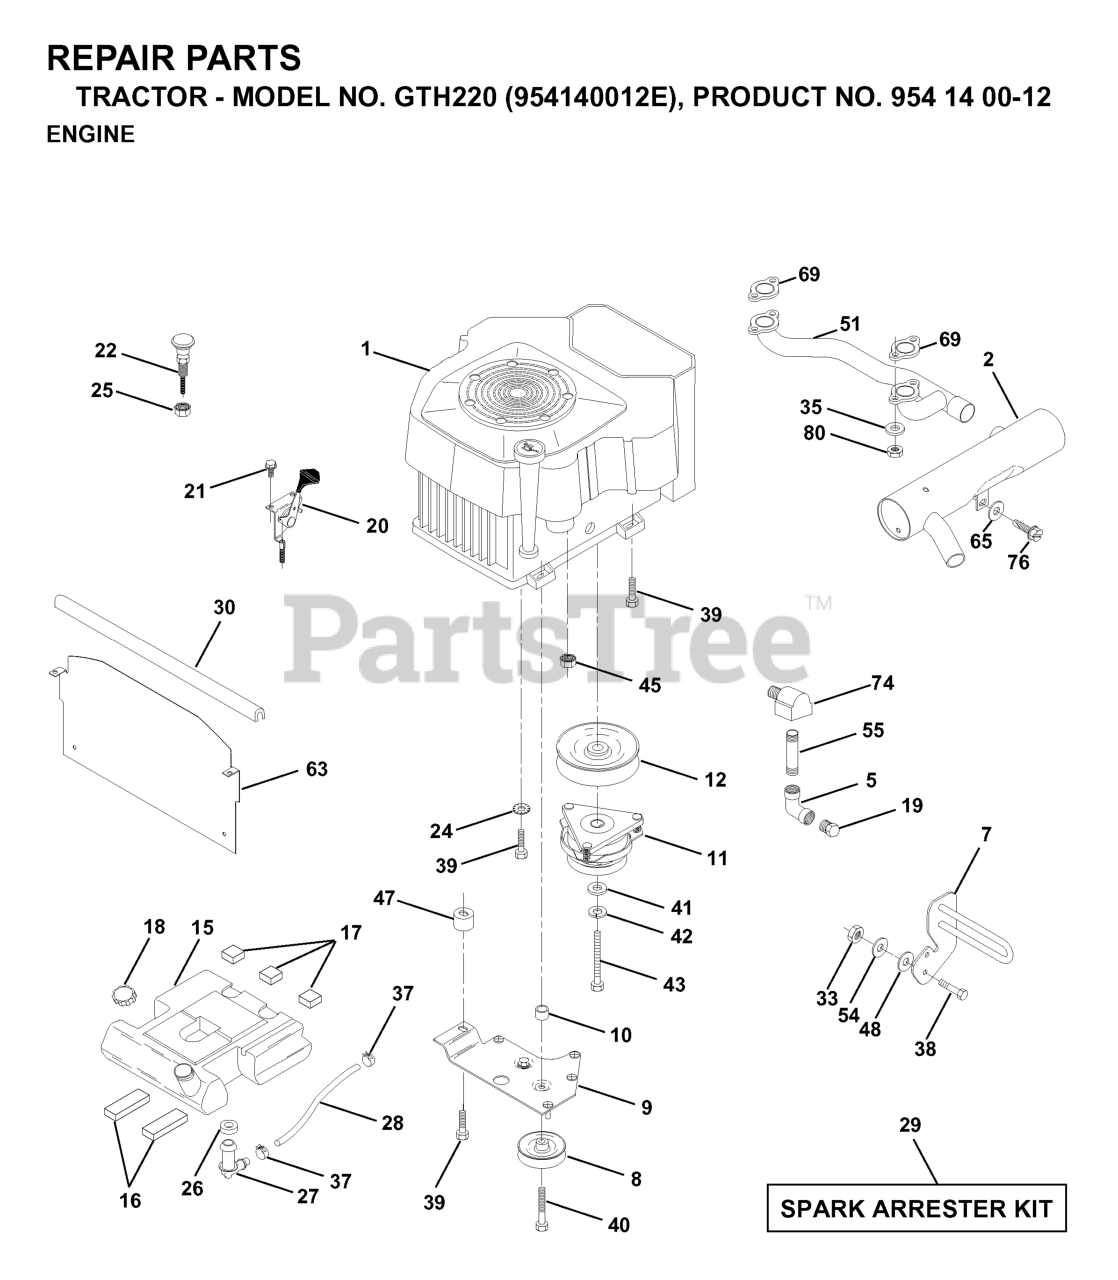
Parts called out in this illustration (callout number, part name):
5	ELBOW
8	RP.IDLER GROOVED
9	KEEPER ASM. BELT ENGINE VGT 96
11	CLUTCH ELECTRIC
12	PULLEY ENG VGT ELECT CLUTCH
15	FUEL TANK 3.5G
16	PAD IDLER TI
17	PAD-SPACER LT
18	FUEL CAP
20	THROTTLE CONTROL
21	SCREW LT
22	CHOKE CONTROL
24	LOCKWASHER
25	Nut Keps 3/8 - 24 UNF
26	BUSHING OUTLET T
27	STEM FUEL TANK
28	HOSE
30	EXTRUSION HOOD
33	NUT
37	HOSE CLAMP
38	BOLT
39	SCREW TT 3/8-16X2-1/4 UNC
40	Screw TT 3/8-16 x 4 unc
42	LOCKWASHER
43	BOLT HEX
45	NUT FLANGE 1/4-20 STARTER NUT
47	SPACER.ENGINE.CV22.ROUND.PM
48	Washer 13/32 x 1-1/4 x 7 Ga.
51	MANIFOLD PIPE VGT
55	Nipple, Pipe 3/8 NPT x 4-1/2
63	SHIELD, HEAT VGT YP/HUSQ
65	WASHER
74	ELBOW STREET BRASS
76	SCREW
80	FLANGE NUT
